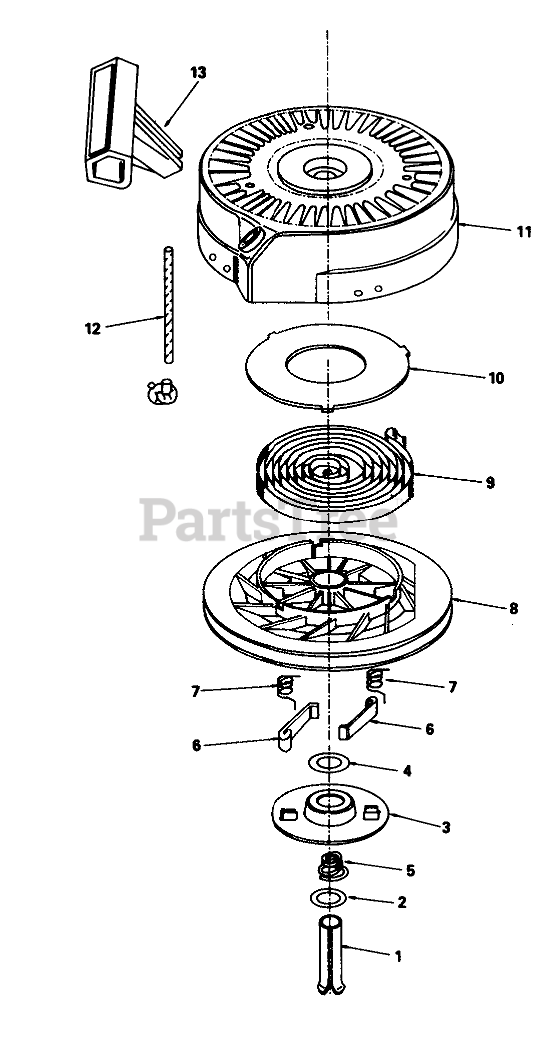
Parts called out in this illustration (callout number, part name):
1	Pin Spring
3	Retainer
5	Brake Spring
6	Dog-Starter
7	Spring-Dog
8	Pulley
9	Rewind Spring
10	Cover-Spring
11	Housing-Starter
12	Rope-Starter (98 cut to length)
13	Handle-Starter
